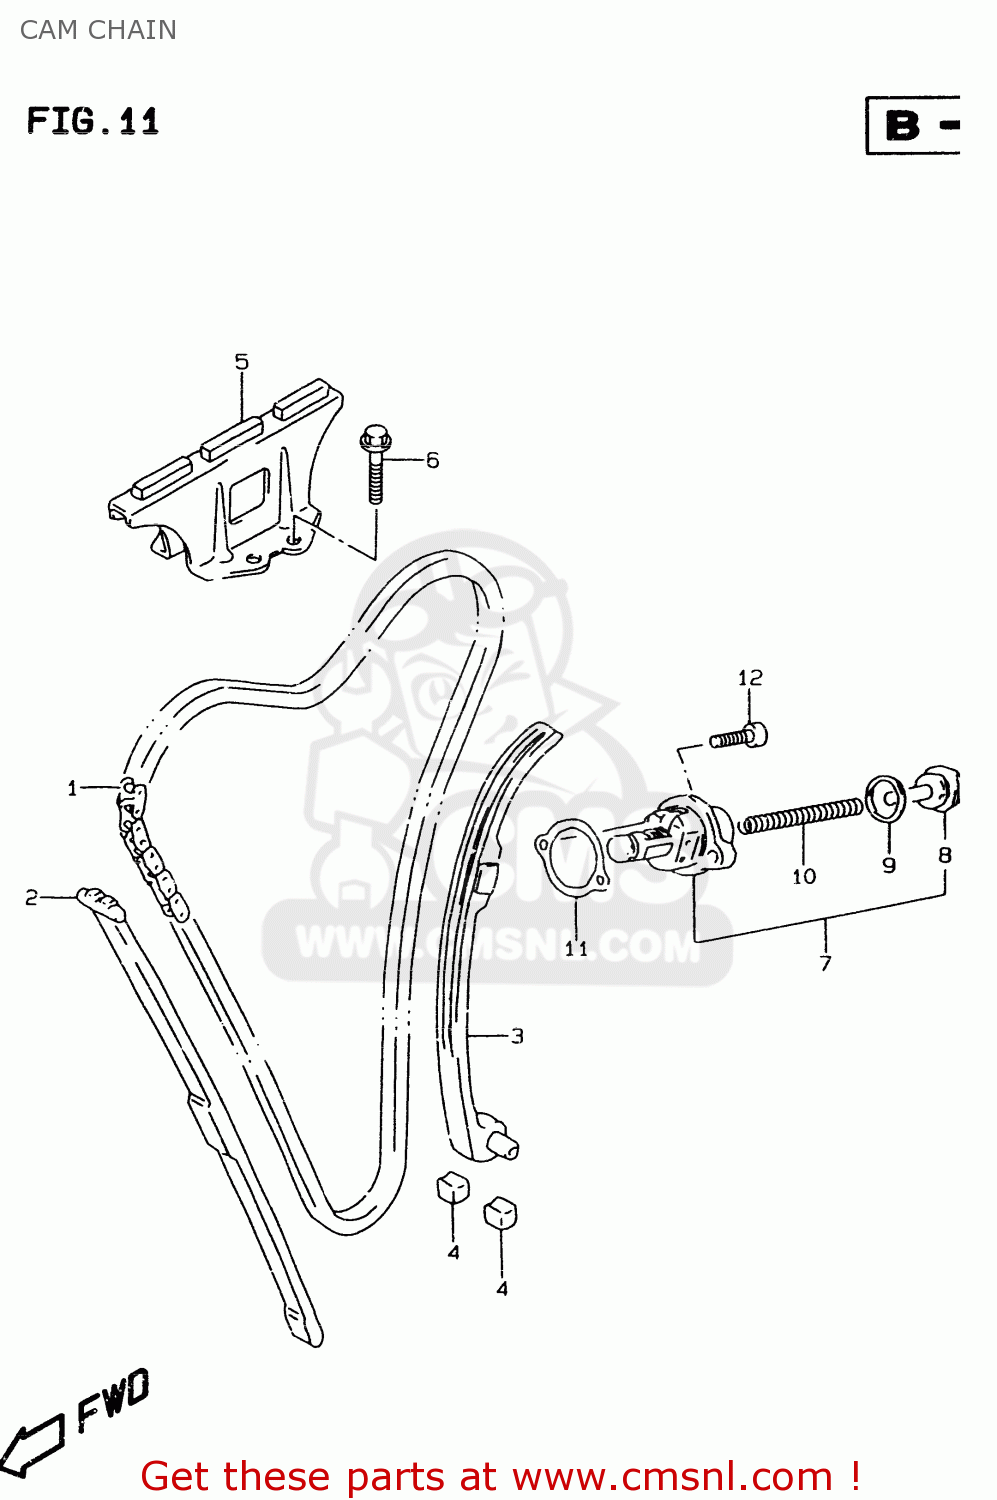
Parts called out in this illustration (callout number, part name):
1	CHAIN,CAMSHAFT DRIVE
2	GUIDE,CAM CHAIN NO.1
3	TENSIONER,CAM CHAIN
4	CUSHION,CAM CHAIN TENSIONER
5	GUIDE,CAM CHAIN NO.2
6	BOLT
7	ADJUSTER ASSY,TENSIONER
8	PLUG
9	GASKET (NAS)
10	SPRING
11	GASKET,TENSIONER ADJUSTER (NAS)
12	BOLT,CL.COVER
